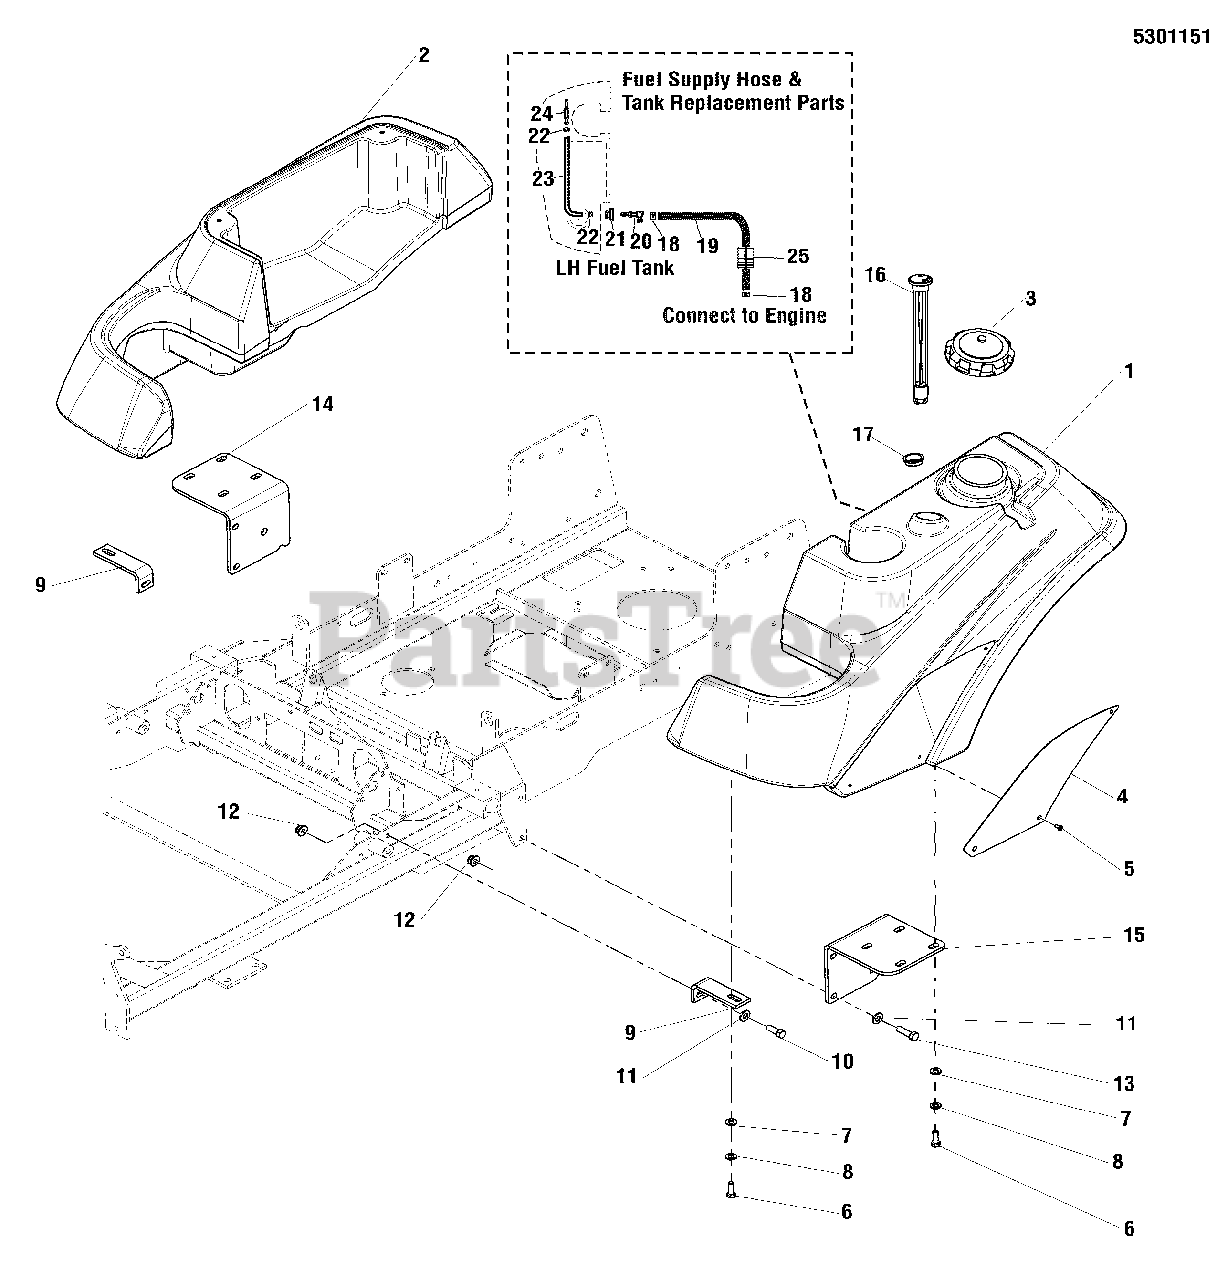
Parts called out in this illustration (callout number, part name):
2	TANK, FENDER, CITATION/ZT4000 - RH
4	BADGE, CITATION, ORANGE
5	SCREW, #10-24 X 3/8 ALLEN BHBZ
6	BOLT, 5/16-18 X 1 GD5 YZ
7	WASHER, 5/16 GD.9 FLAT
8	WASHER, 5/16 LOCK YZ
9	MOUNT, TANK, FRONT - BLK
10	BOLT, 3/8-16 X 1 GD5 YZ
11	WASHER, 3/8 GD.9 FLAT
12	NUT, 3/8-16 HEX NYLOCK FLANGE
13	BOLT, 3/8-16 X 1-1/4 GD5
14	WELD, TANK MOUNT-RH-BLK
15	WELD, TANK MOUNT-LH-BLK
16	GUAGE, FUEL LEVEL
18	CLAMP, HOSE, EXTERNAL, 1/2
19	HOSE, FUEL, 1/4 IN, LW PRMTN
23	HOSE ASSEMBLY
25	WIRE LOOM, 1/2 ID, 20.00 LONG
